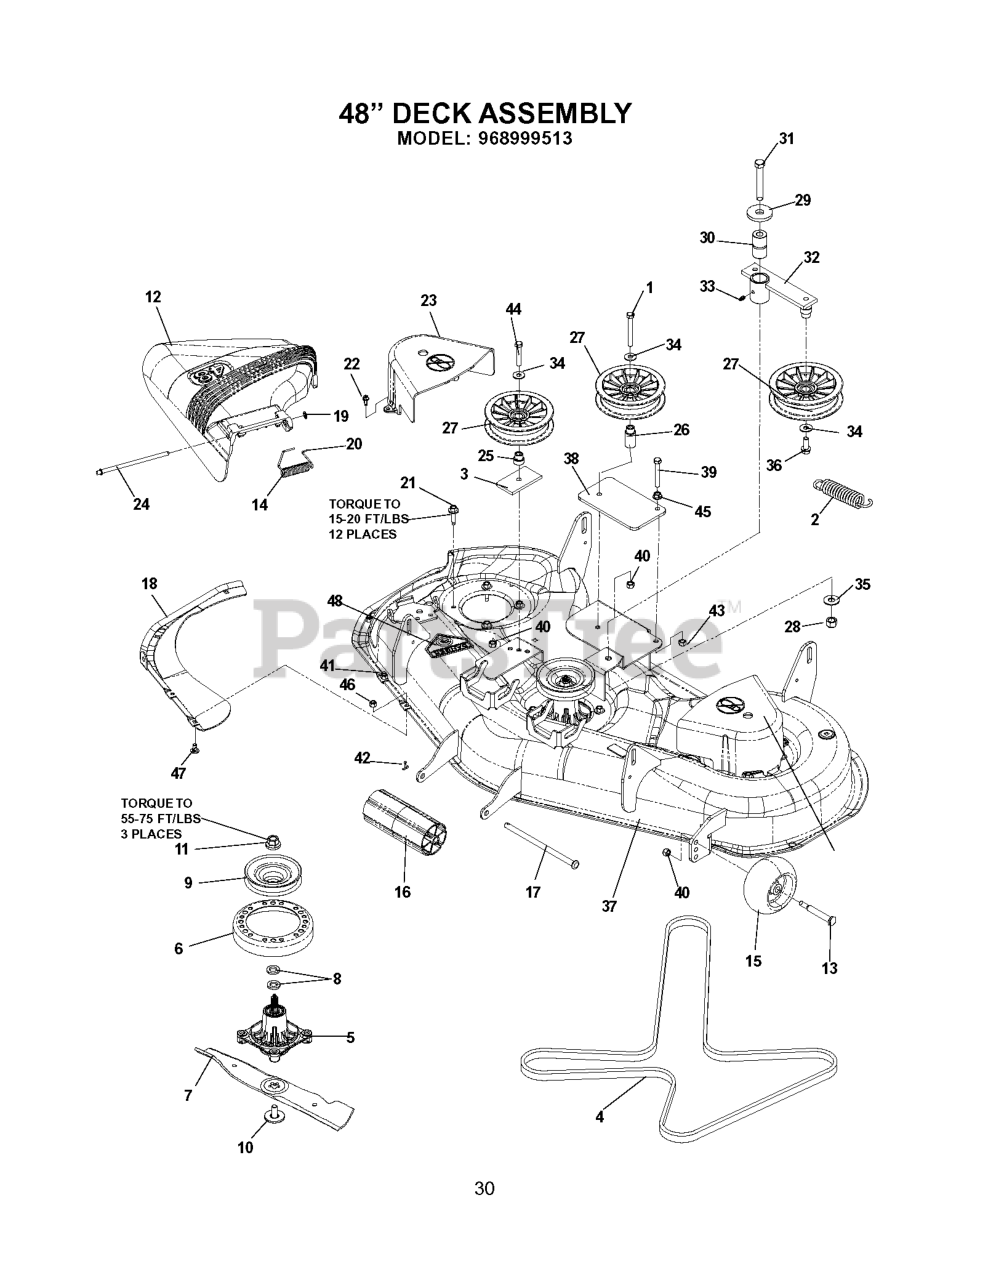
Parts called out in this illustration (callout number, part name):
1	HCS 3/8C X 3
3	SUPPORT PLATE
4	BELT, DECK
5	MANDREL ASM
6	STRIPPER-ROUND-UNIVERSAL
7	48" HI-LIFT BLADE
8	WASHER-SPACER
9	PULLEY.DRIVEN.DECK.48'
10	BOLT 7/16 ASM BLADE
11	LOCKNUT - 9/16
12	DISCHARGE CHUTE
13	BOLT, SHOULDER
14	TORSION SPRING
15	WHEEL GAGE DONUT
16	NOSE ROLLER 48"
17	NOSE ROLLER ROD
18	VORTEX MOWER BAFFLE
19	PUSH NUT
20	CAP-SLEEVE
21	WASHER HEAD SCREW
22	SCREW- 1/4-20 X 5/8
23	BELT SHIELD
24	ROD.HINGE
25	IDLER BUSHING
26	IDLER BUSHING
27	IDLER
28	NUT 1/2-13 HEX NYLOC ZD
29	WASHER, SUPPORT
30	PIVOT BUSHING
31	HCS 1/2C X 3 1/4
33	ZERK
34	WASHER 3/8 FLAT
35	WASHER 1/2 FLAT
36	4CS 3/8C X 1 SERRATED HEAD
37	DECK W/DECALS 48 WSL
38	SUPPORT PLATE, BLACK
39	HCS 3/8C X 2.5" GRADE 8
40	NUT 3/8-16 NYLOC
41	SCREW 5/16C X 1 HEX CAP
42	RP_COTTER PIN 1/8 X 3/4
43	NUT 3/8C CENTERBLOCK
44	HCS 3/8C X 2
45	NUT 3/8C WHIZ
46	NUT 5/16 NYLOC
47	CARRIAGE BOLT 5/16C X 5/8"
48	DECAL, CPSC
